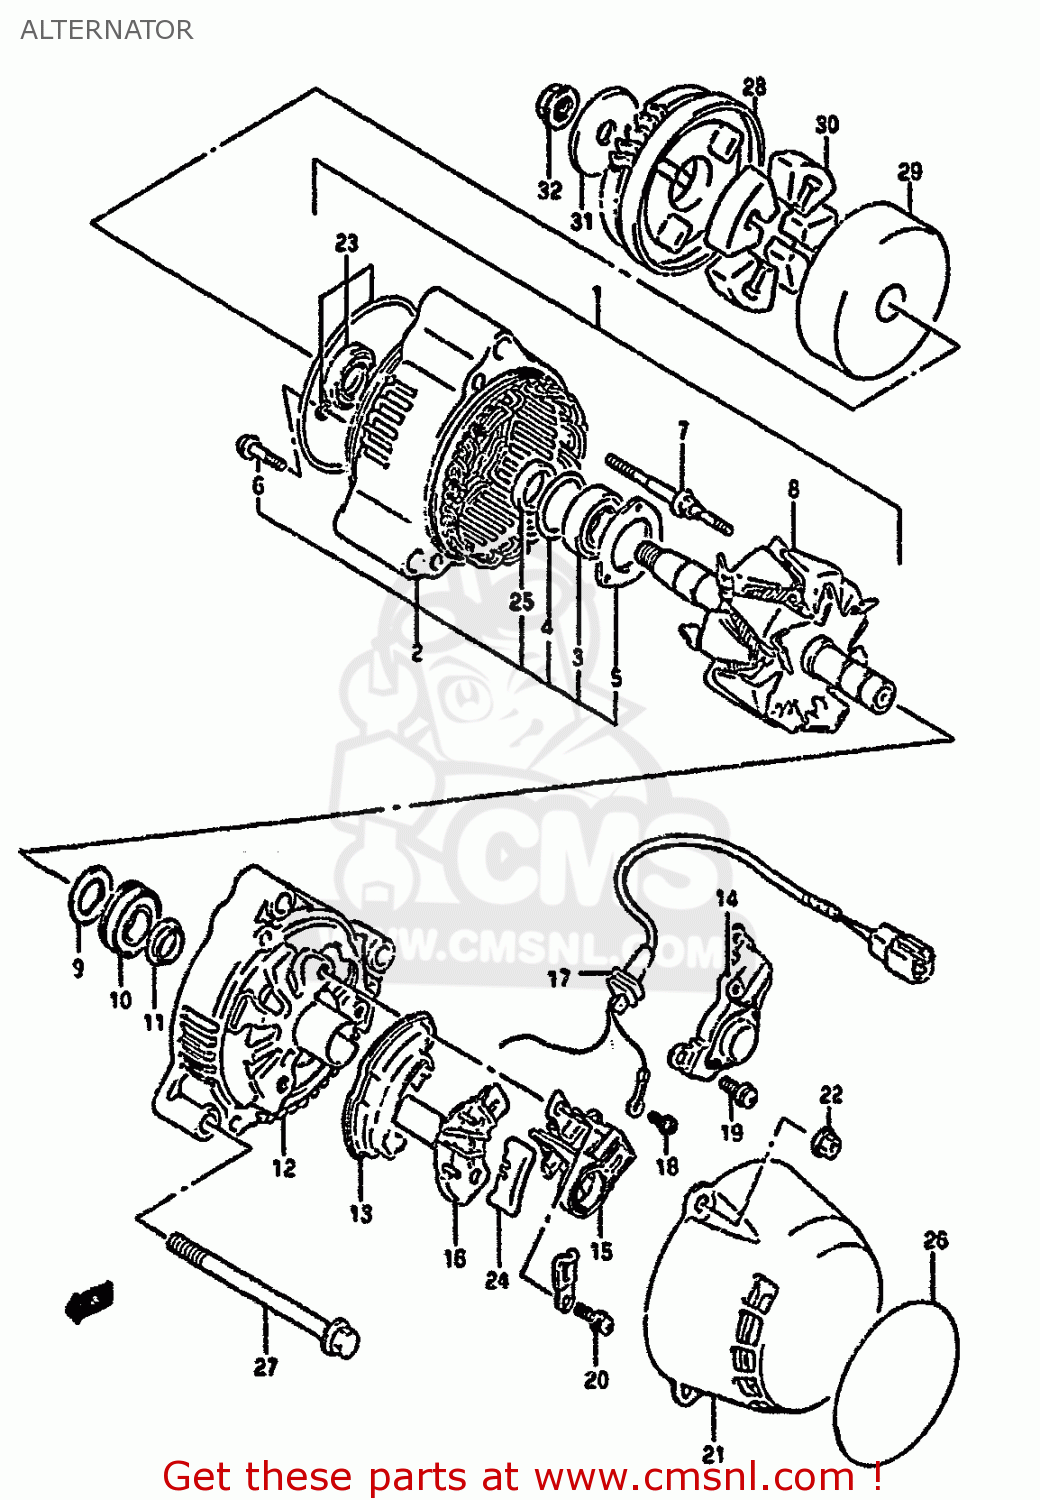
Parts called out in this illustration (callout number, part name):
1	ALTERNATOR ASSEMBLY
2	FRAME,DRIVE END
3	BEARING
4	COVER,BEARING
5	RETAINER
6	SCREW,BEARING RETAINER
7	STUD BOLT
8	ROTOR ASSEMBLY
9	COVER,BEARING
10	BEARING
11	COVER(2)
12	FRAME,END
13	HOLDER,RECTIFIER
14	REGULATOR
15	HOLDER,BRUSH
16	COVER,RECTIFIER
17	WIRE,LEAD
18	SCREW 4X6
19	SCREW
20	SCREW
21	COVER
22	NUT ,5MM
23	SEAL SET,OIL
24	BUSH
25	SPACER
26	PROTECTOR,ALTERNATOR
27	BOLT
28	GEAR COMP,GENERATOR DRIVE
29	HOUSING,GENERATOR GEAR
30	DAMPER,GENERATOR DRIVE
31	WASHER (10X36X2)
32	NUT
